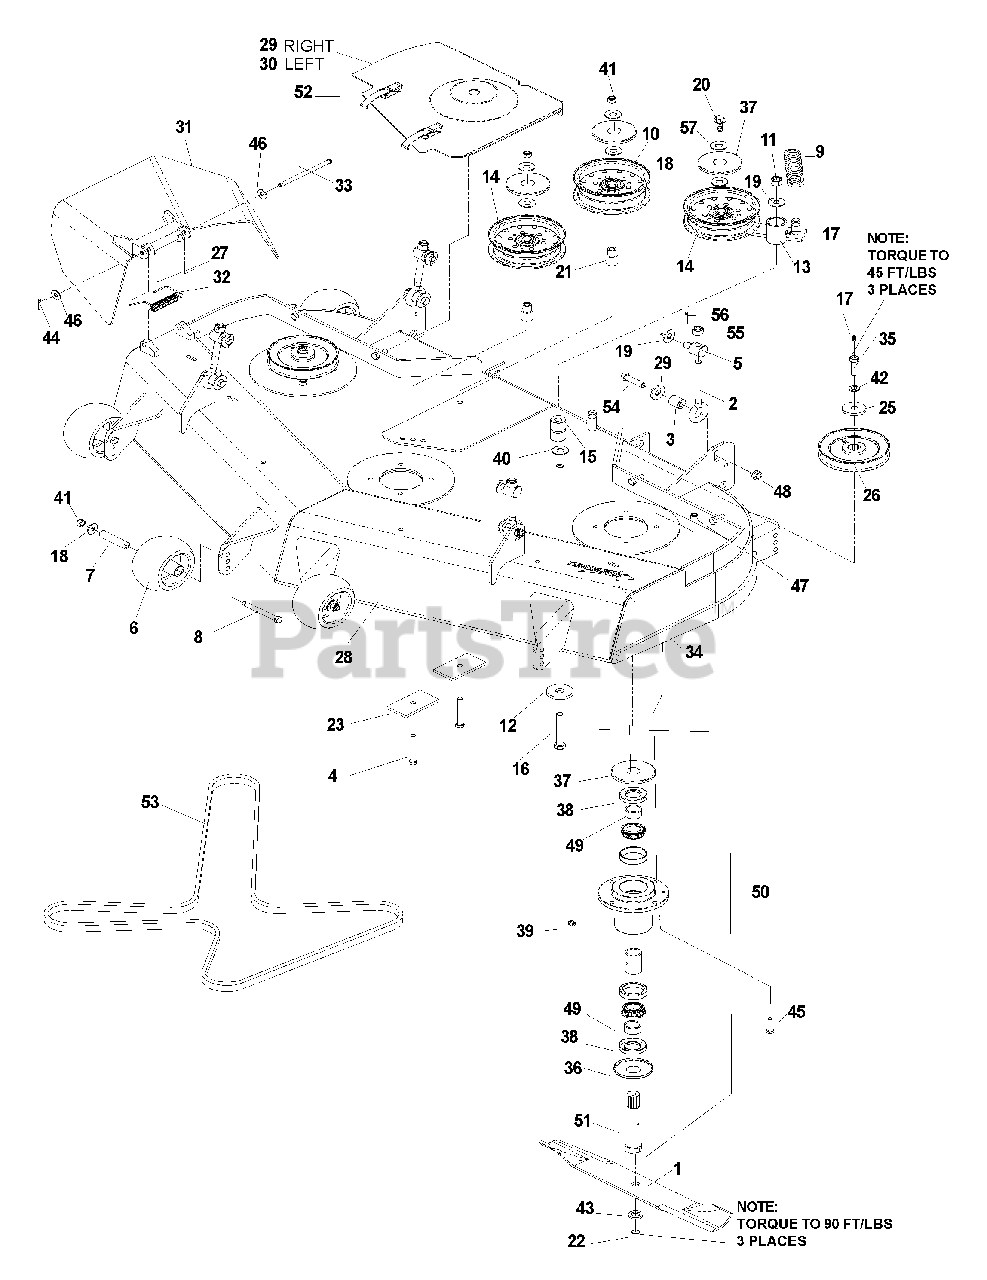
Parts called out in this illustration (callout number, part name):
1	BLADE, 18"
4	HCS, 3/8-16 X 2 3/4, GR5
6	ROLLER, ANTI SCALP
8	HCS, 3/8-16 X 3 1/2, GR8
9	SPRING, EXTENSION
10	PULLEY, IDLER
11	NUT, 1/2-13, NYLOC
12	WASHER, .65
14	PULLEY, IDLER
15	BUSHING, PIVOT
16	HCS, 1/2-13 X 3 1/4, GR5
17	ZERK, STRAIGHT, 1/4-28
18	WASHER, 3/8
19	WASHER, 9/16
20	HCS, 3/8-16 X 1,GR5
21	BUSHING, IDLER
22	HCS, 5/8-18 X 1 1/4, GR5
23	PAD
24	SPRING WASHER, 1/2
25	WASHER, .469
27	CAP-SLEEVE
28	DECK W/DECALS
29	BELT SHIELD, RIGHT
30	BELT SHIELD, LEFT
31	DISCHARGE CHUTE
32	SPRING, TORSION
33	PIN-CLEVIS, 5/16 DIA. X 5.19
34	DECAL, TUNNELRAM
35	HCS, 7/16-20 X 1 1/2, GR8, SPEC
36	BOTTOM DUST CAP
37	TOP DUST CAP
38	SHAFT SEAL
39	PLUG, VENTED
40	WASHER, 1/2
41	NUT, 3/8-16, NYLOC
42	LOCKWASHER, 7/16
43	LOCKWASHER, 5/8
44	PIN COTTER, 1/8 X 3/4
45	HCS, 5/16-18 X 1 1/4, GR5
46	WASHER, 5/16
47	NUT, 5/16-18, NYLOC
48	NUT, 7/16-14, CENTERLOCK, GR A
49	TOP & BOTTOM SPACER
50	SPINDLE ASSEMBLY
52	DRAW LATCH
53	DECK BELT
54	HCS, 7/16-14 X 1 3/4, GR5
55	NUT, 1/2-13, NYLOC
56	PIN, COTTER, 1/8 X 1
57	WASHER, 3/8, SPEC
